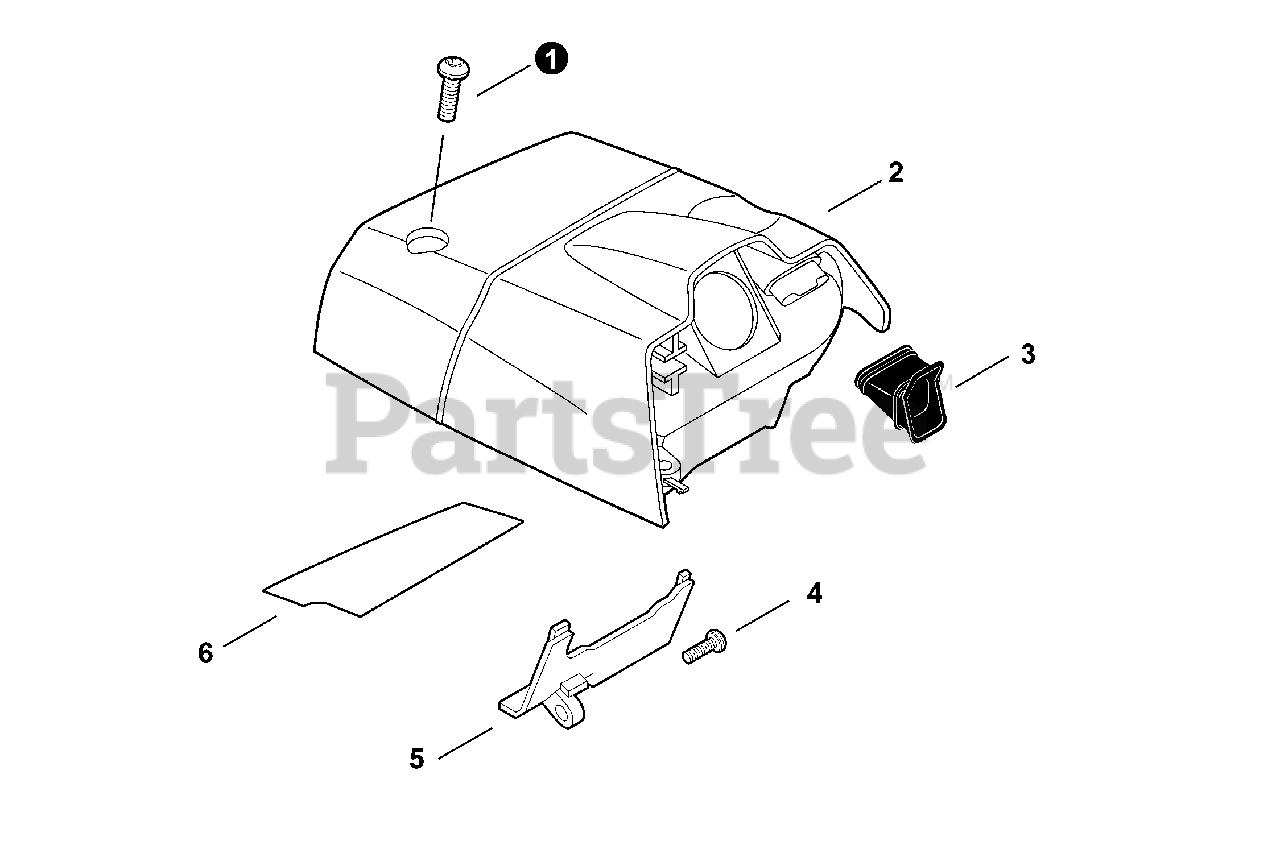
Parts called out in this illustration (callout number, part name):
1	BOLT, TORX 5×16
2	COVER, ENGINE
3	PIPE, INTAKE
4	BOLT, TORX 5×16
5	GUIDE, AIR
6	SHIELD, HEAT 75×32×0.15
